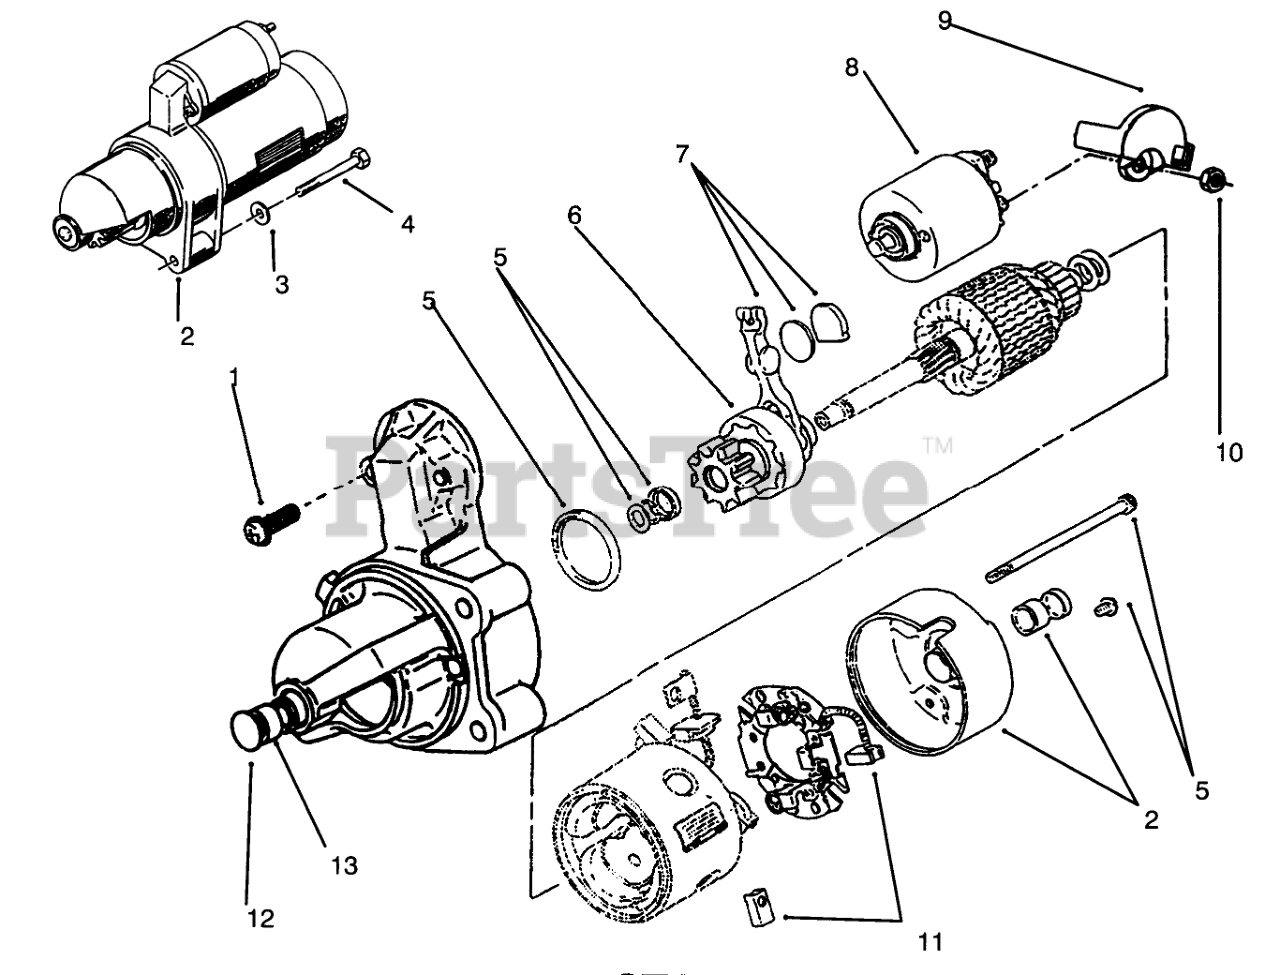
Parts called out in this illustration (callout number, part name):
1	Starter Hdwr Kit (Incl. Solenoid Screws 2] Brush Holder Screws 2], Thru Bolts2], Armature Shims 2], Pinion Stop Collar, & Pinion Retaining Ring)
2	STARTER
3	WASHER
4	SCREW
5	DUST-SEAL KIT
6	Clutch-Starter (Incl. Pinion Gear w/Clutch)
7	Kit-Starter Shift Lever (Incl. Shift Lever, Wear Plate & Rubber Plug)
8	Kit-Starter Solenoid (Incl. Solenoid, Spring, & Plunger)
9	Cap-Starter Solenoid
10	Nut
11	Kit-Starter Brush (Incl.Positive Brush 2] & Negative Brush w/Pigtail)
12	Kit-Bushing (Incl. Front Bushing & Rear Capw/Bushing)
13	Holder-Starter Brush (Incl. Brush Holder w/Negative Brush)
